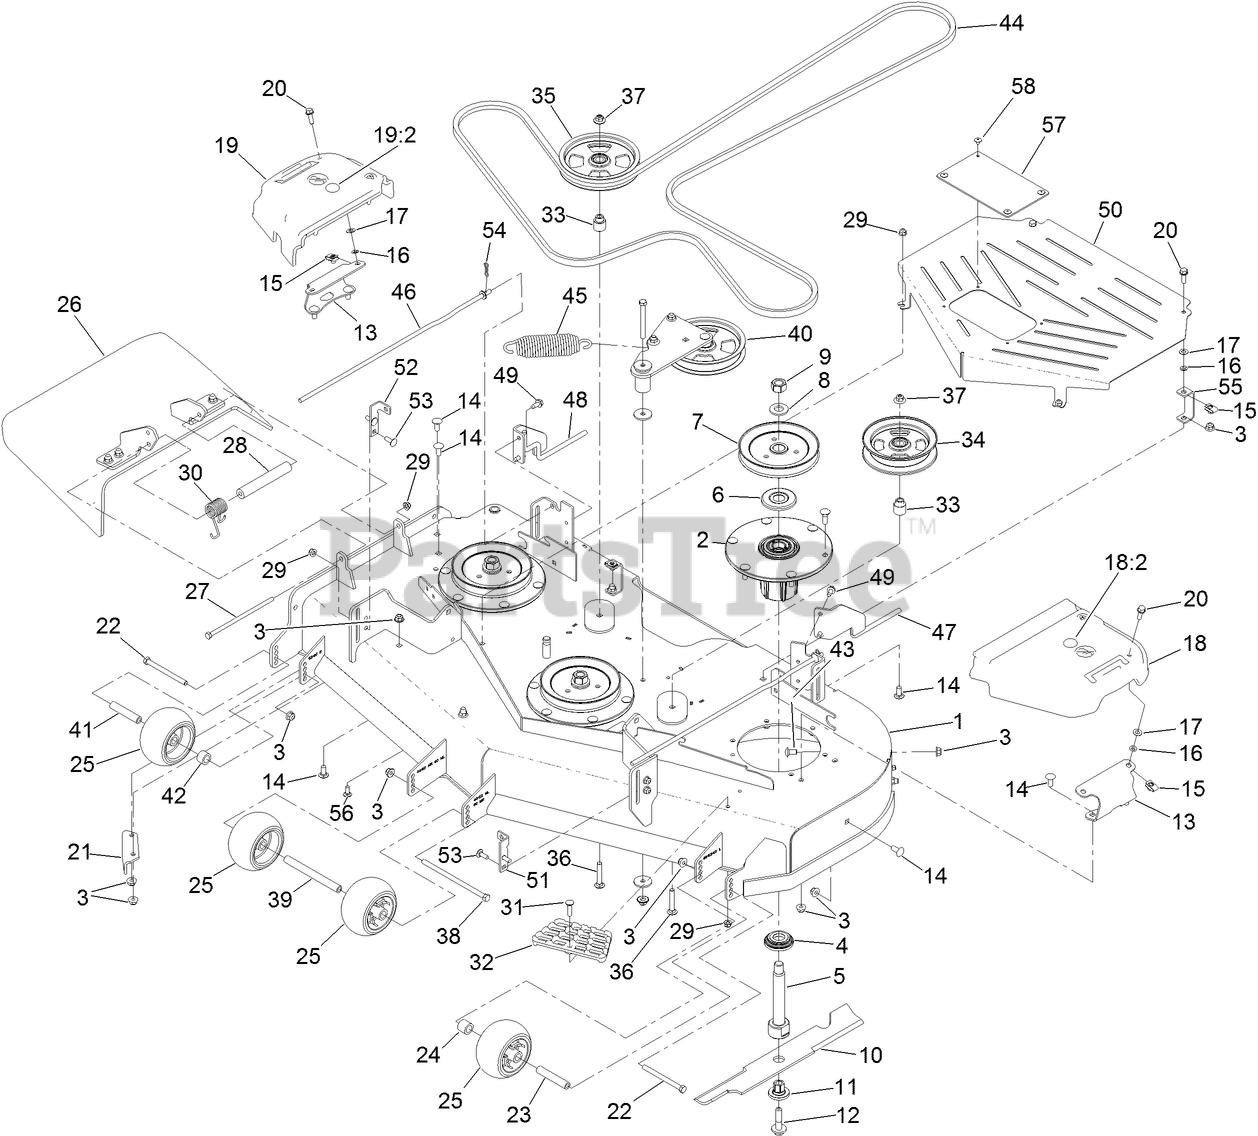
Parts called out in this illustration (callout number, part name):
1	DECK DECAL ASM
2	SPINDLE ASM
3	NUT-HF, NI
4	GUARD-BOTTOM
5	SHAFT-SPINDLE
6	GUARD-BEARING, TOP
7	SHEAVE-BLADE DRIVE 6.50
8	WASHER
9	NUT-HEX
10	BLADE-FLOW, HIGH
11	BUSHING-HEX
12	SCREW-SEMS
13	BRACKET-COVER, BELT
14	SCREW-CARR
15	NUT-U
16	NUT-PUSH
17	WASHER-THRUST
18	LH BELT COVER ASM
18:2	PLUG-PLASTIC
19	RH BELT COVER ASM
19:2	PLUG-PLASTIC
20	SCREW-HHF
21	BAFFLE-DISCHARGE
22	SCREW-HH
23	TUBE-SPANNER
24	TUBE-SPACER
25	ROLLER-SCALP, ANTI
26	RUBBER DEFLECTOR ASM
27	SCREW-HH
28	SPACER
29	NUT-HF, NI
30	SPRING-TORSION
31	SCREW-CARR
32	STEP-DECK
33	BUSHING, IDLER
34	PULLEY-IDLER, FLAT
35	PULLEY-IDLER, FLAT
36	SCREW-CARR
37	NUT-FLANGE, NI
38	SCREW-HH
39	SPACER-WHEEL
40	IDLER ARM ASM
41	TUBE-SHAFTING
42	TUBE-SPACER
43	SCREW-CARR
44	BELT-V
45	SPRING-EXTENSION
46	ROD-SKIRT, LOWER
47	SUPPORT-LOWER LH
48	SUPPORT-LOWER RH
49	SCREW-HWHTF
50	GUARD-CENTER BELT 52
51	BRACKET-SUPPORT, LH
52	BRACKET-SUPPORT, RH
53	BOLT-CARR
54	PIN-COTTER, LOCKING
55	BRACKET-GUARD
56	SCREW-CARR
57	SHIELD-RUBBER
58	RIVET-POP
